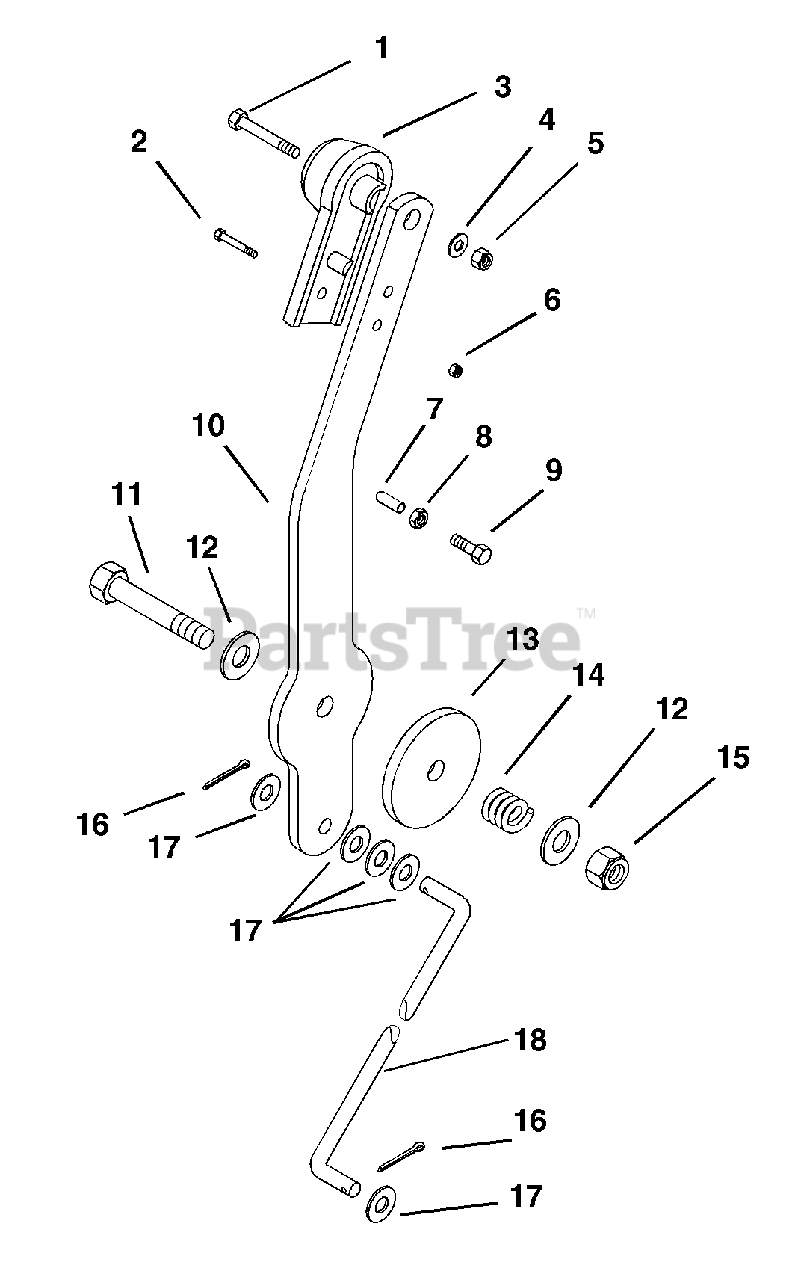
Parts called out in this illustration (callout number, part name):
1	@BLT-HEX .25-20X1.50 GR5 YWZC
2	SCR-MCH 6-32X.625
3	KNOB,HANDLE CONTROL
4	@WSHR-FL-STL.281X.62X.065 YWZC
5	@NUT-LK-CTR .25-20 YWZC
6	@NUT-LK-NYL 6-32 W/INSRT YWZC
7	CAP,
8	@NUT-HEX .25-20 YWZC
9	@BLT-HEX .25-20X.75 GR5 YWZC
10	LVR,SPEED CTL
11	@BLT-HEX .50-13X2.50 GR5 YWZC
12	@WSHR-FL-STL.531X1.06X.095YWZC
13	DISC,FRICTION MAT'L
14	SG-COMP .125X.78X1.00 YWZ
15	@NUT-LK-CTR .50-13 YWZC
16	@PIN-CTR .09X1.00 EXTPRSQCT YZ
17	@WSHR-FL-STL.406X.812X.065 YWZ
18	ROD,SPEED CONTROL
